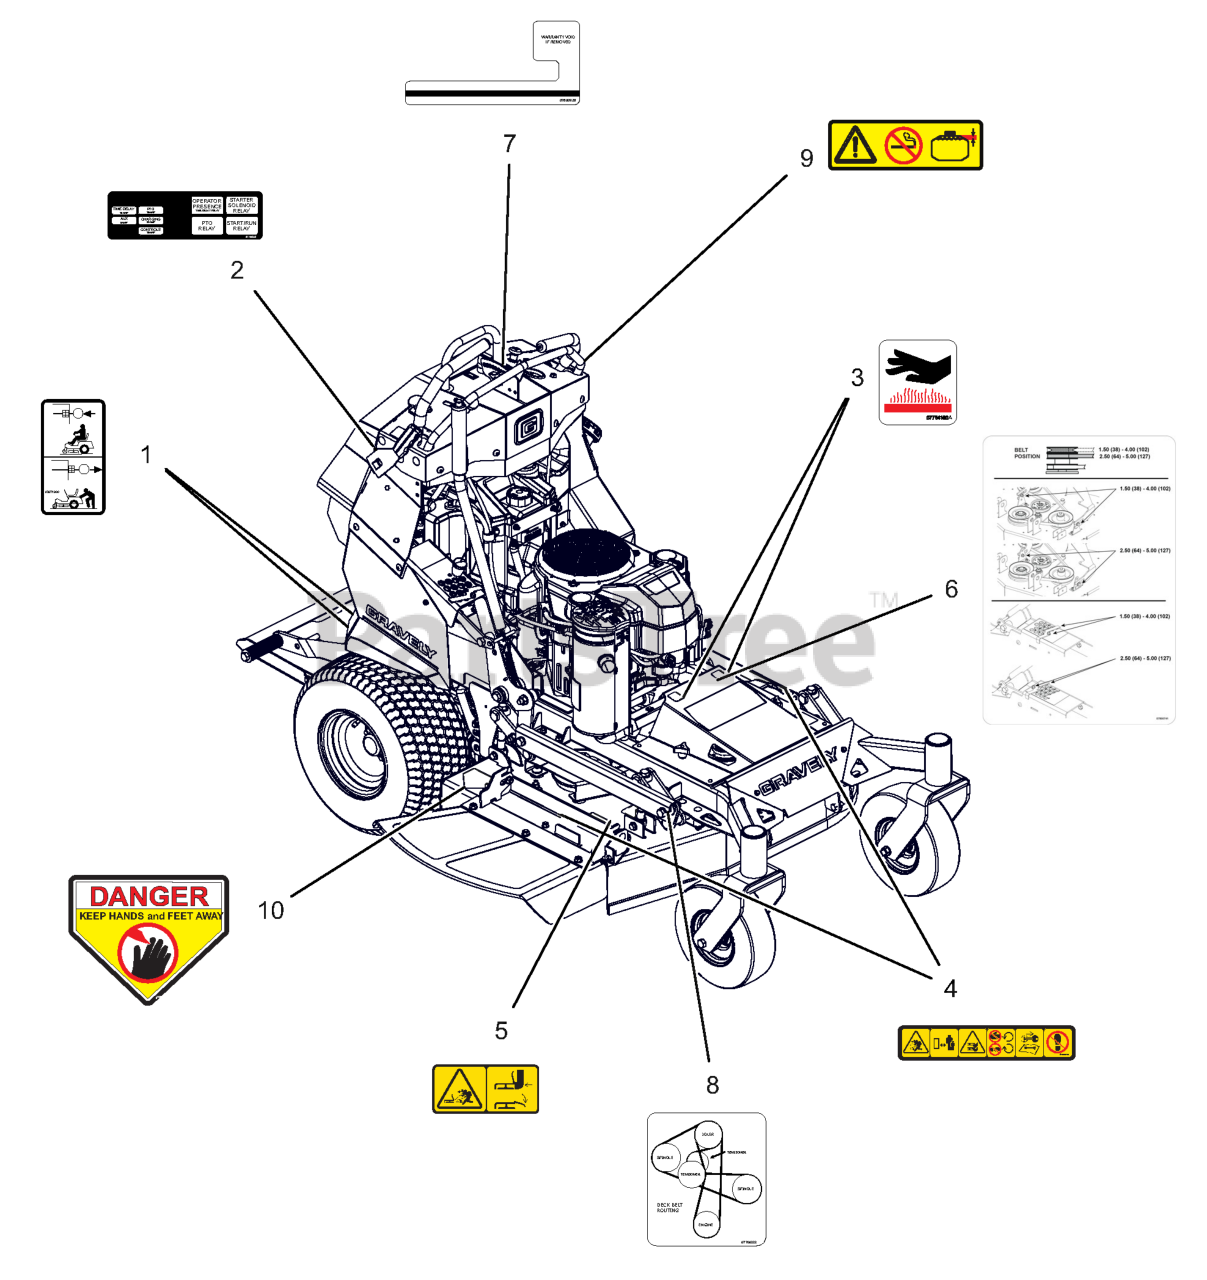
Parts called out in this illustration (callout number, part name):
1	DECAL, TRANSMISSION DISCONNECT
2	DECAL, FUSE BOX
3	DECAL, HOT SURFACE
4	DECAL, DECK SAFETY
5	DECAL, SAFETY - DECK GUARDING
6	DECAL- 32-36 PS HOC ADJUSTMENT
7	DECAL,HOURMETER - SECURITY
8	DECAL, BELT RTG 32-36" PROSTANCE
9	DECAL, FUEL WARNING
10	DECAL, DANGER
